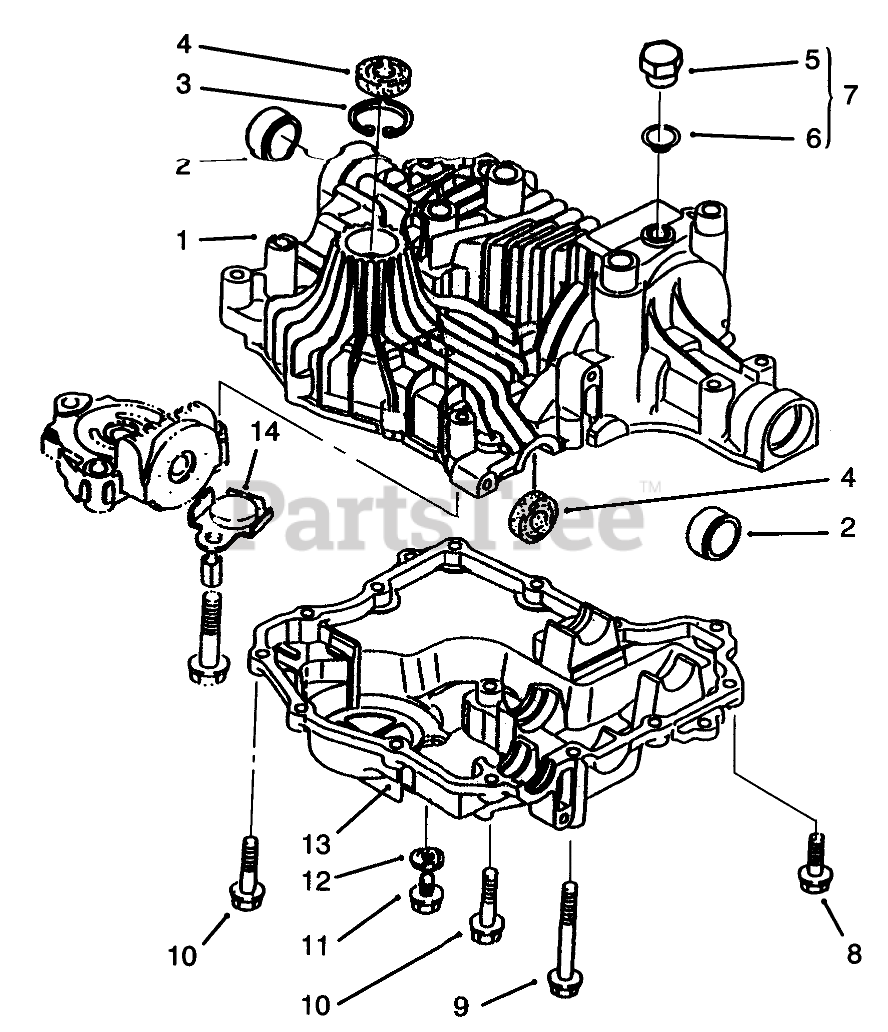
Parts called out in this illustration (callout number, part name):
1	Upper Case ASM INCL 2-6 (Only On: 72043, 72063, 72103)
3	Ring (Only On: 72043, 72063, 72103)
4	Seal (Only On: 72043, 72063, 72103)
7	Plug/Packing INCL 5-6 (Only On: 72043, 72063, 72103)
8	Screw-TAP (Only On: 72043, 72063, 72103)
9	Bolt (Only On: 72043, 72063, 72103)
10	Screw-TAP (Only On: 72043, 72063, 72103)
11	Bolt (Only On: 72043, 72063, 72103)
13	Case-Lower (Only On: 72043, 72063, 72103)
14	Magnet (Only On: 72043, 72063, 72103)
